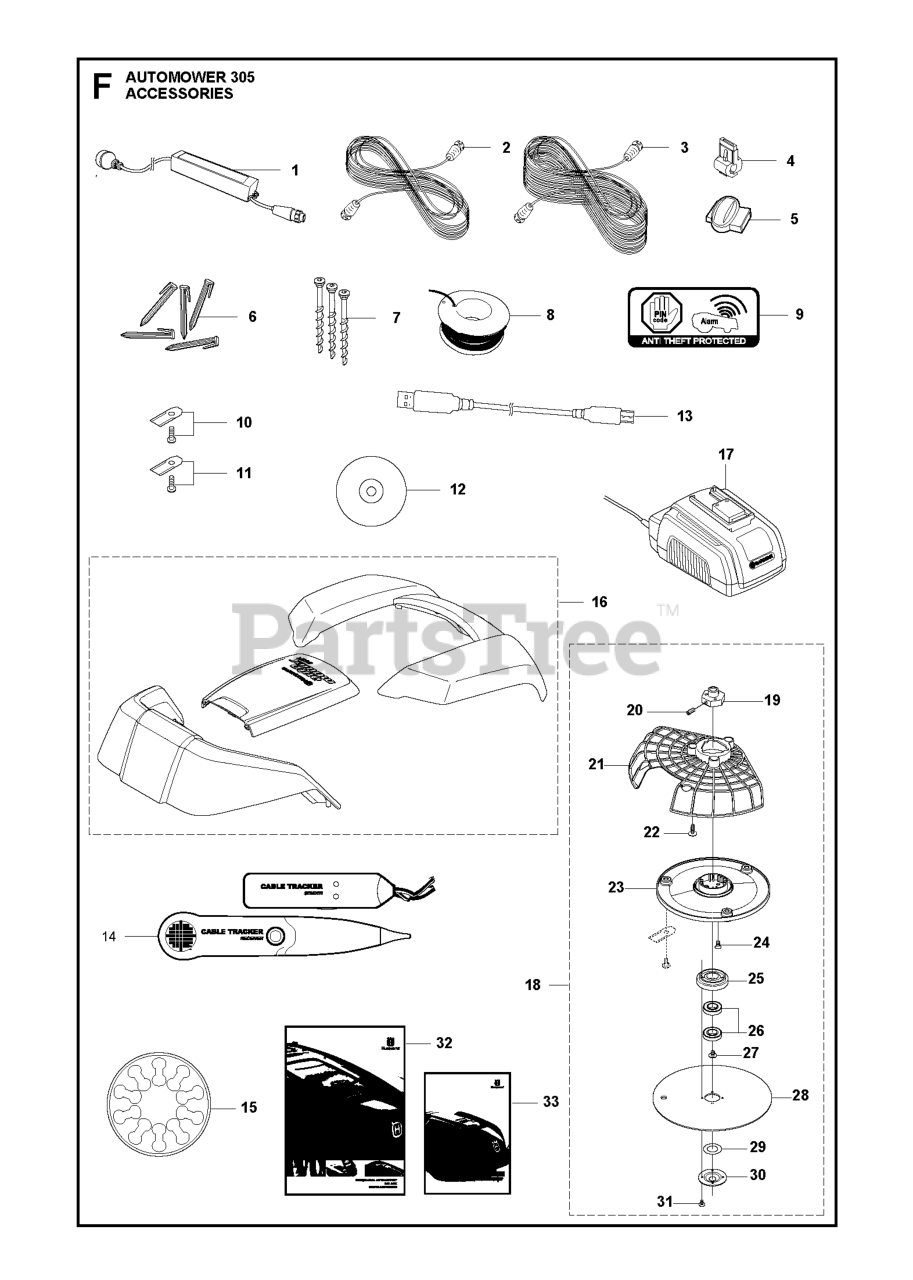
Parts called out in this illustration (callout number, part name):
4	CONNECTOR 5 PCS, BLISTER
4	BRAKER
5	COUPLER SPLICER, 5 PCS,
5	SPLICE CONNECTOR 50 PCS/PK
5	SPLICE KIT
6	STAPLES (100 CT BAG)
6	STAPLE 100 PCS, BLISTER
7	SCREW KIT KIT INCLUDES THREE S
7	SCREW 3 PCS, BLISTER PACK
8	WIRE 150M, BLISTER
8	LOOP WIRE 150M
8	LOOP WIRE 250M
10	BLADE - 30 PCS
10	BLADE
10	BLADE - BULK PACK 500 PCS
10	BLADE KIT
11	BLADE 300PCS -SINGLE HOLE THIC
11	BLADE BLADE KIT INCL PACKAGING
11	BLADE CARBON STEEL, THICK BLAD
11	BLADE 9PCS EXTRA THICK
14	TEST EQUIPMENT
20	SCREW IHSETM M5X10 8.8 ZP-BC
22	SCREW 14MM
24	SCREW
26	BALL BEARING BALL BEARING 535
30	COVER SKID PLATE
31	SCREW SILVER 10MM
